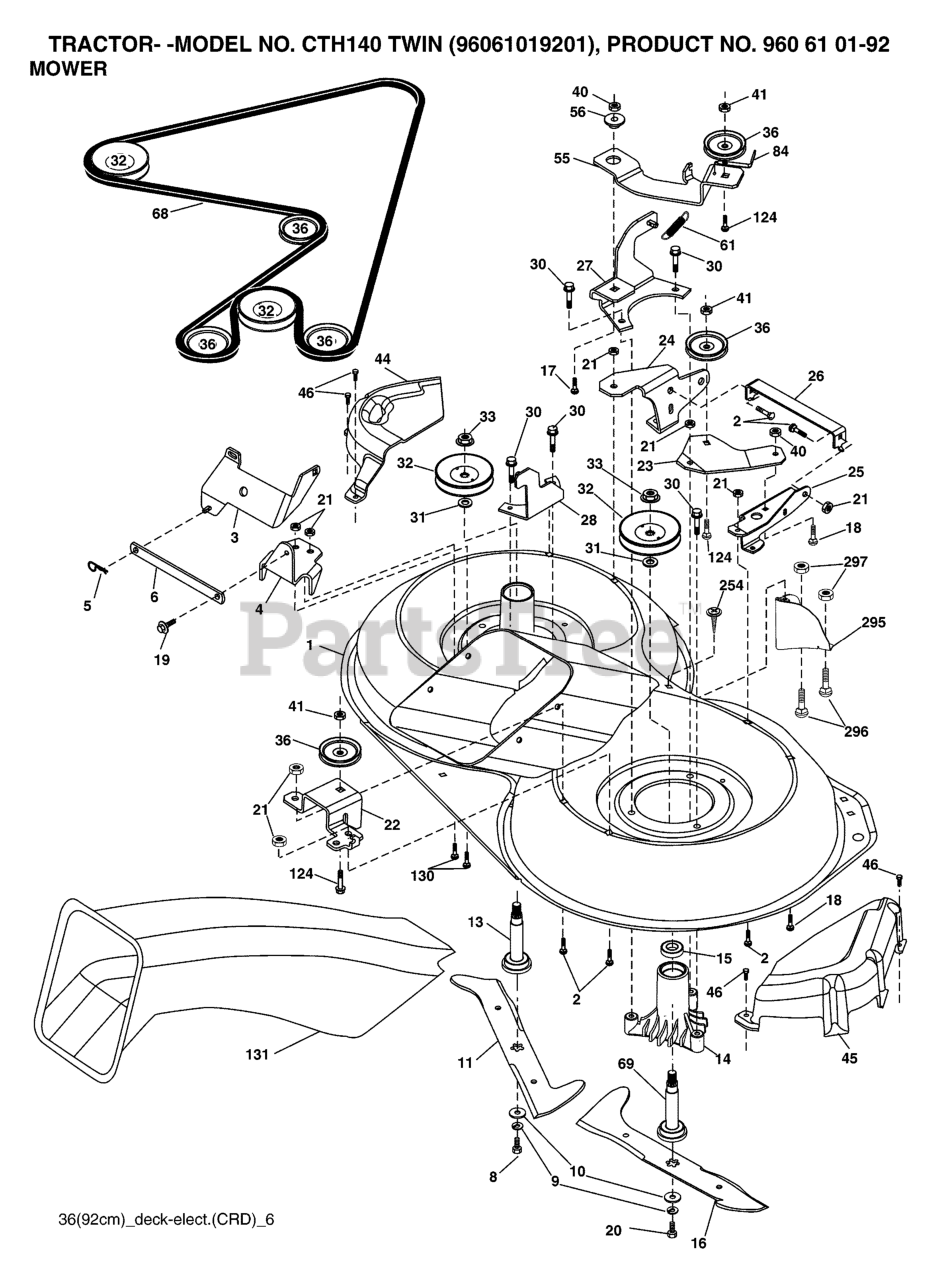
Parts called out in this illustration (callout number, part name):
2	RP BOLT 5/16-18 X3/4 ZN/YEL GR
5	RETAINER-SPRNG RB
6	BAR.SWAY.92.CRD
8	BOLT.3/8-24X1.25 GR8
9	LOCKWASHER
10	WASHER.BLADE
13	SHAFT ASM VENT
14	HOUSING.MANDREL.VENTED (MACHD)
17	BOLT.3/8-14X1.25
19	BOLT SHD 5/16-18
20	BOLT.3/8-24X1.25GR8. LHTHRD
21	LOCKNUT
26	SUPPORT
30	SCREW, WASHER HEAD
31	WASHER.SPACER.MANDREL
32	PULLEY MANDREL
33	NUT.FLANGE.LOCK.TOP
36	PULLEY.IDLER.4.25
41	NUT LOCK FLG 3/8-16 UNC
45	COVER.MANDREL.RH.CRD
46	SCREW.1/4-20X5/8
55	ARM.IDLER.92 CRD.2006
56	SPACER.RETAINER.MOWER
61	SPRING
68	BELT.DRIVE.92CM.CRD.2006
69	SHAFT.ASM.W/LWR.BRG.RH.THREAD
84	KEEPER, BELT IDLER
116	BOLT.SHOULDER.3/8-16X3-5/8.
117	RP WHEEL. GUAGE RALLY
118	LOCKNUT
119	WASHER
124	BOLT.3/8-16X1.50
130	BOLT.CARR.SQNK.5/16-18UNC.X3/4
131	CHUTE BAGGER
254	SCREW 3/8-16X1
296	BOLT
297	NUT CENTERLOCK
